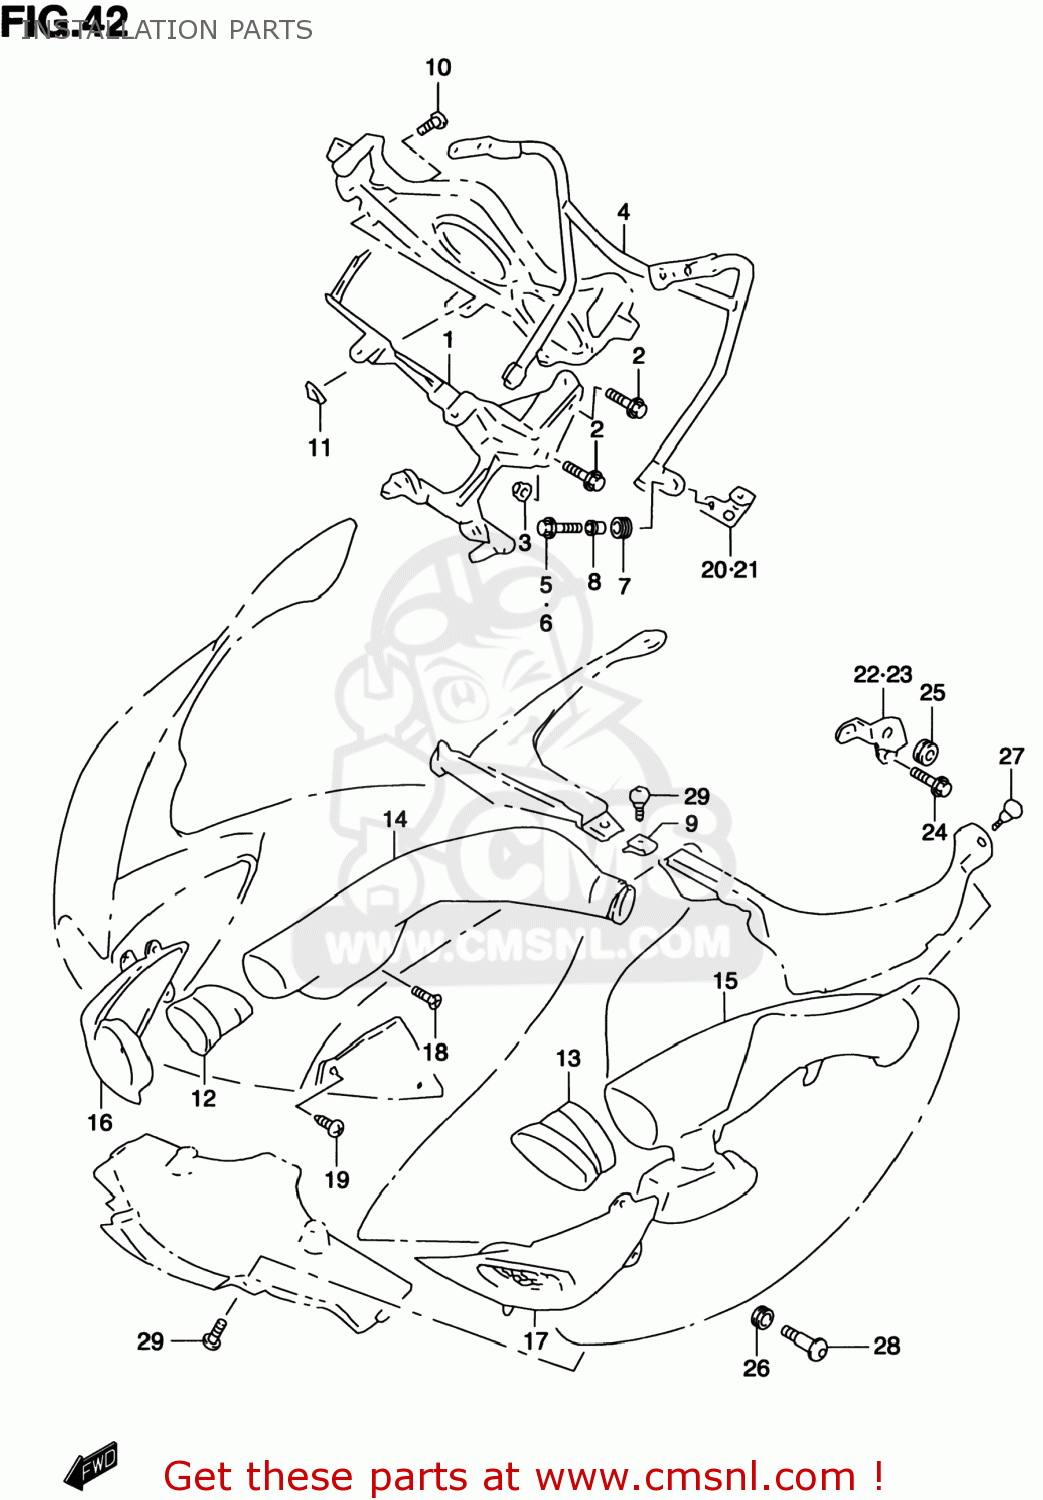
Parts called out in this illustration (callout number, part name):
1	BRACE,COWLING
2	BOLT
3	NUT
4	BRACE,RR VIEW MIRRORR
5	BOLT 6X20
6	BOLT(6X30)
7	CUSHION
8	WASHER,MIRROR BRACE,IN
9	NUT,COWL
10	SCREW
11	NUT
12	JOINT,AIR INTAKE,R
13	JOINT,AIR INTAKE,L
14	PIPE,AIR INTAKE,R
15	PIPE,AIR INTAKE,L
16	COVER,INTAKE,R
17	COVER,INTAKE,L
18	SCREW
19	SCREW
20	BRACKET,SIDE COWLING UP,R
21	BRACKET,SIDE COWLING UP,L
22	BRACKET,SIDE COWLING RR,R
23	BRACKET,SIDE COWLING RR,L
24	BOLT
25	CUSHION
26	CUSHION
27	SCREW(5X16)
28	SCREW(6X20)
29	SCREW(5X16)
